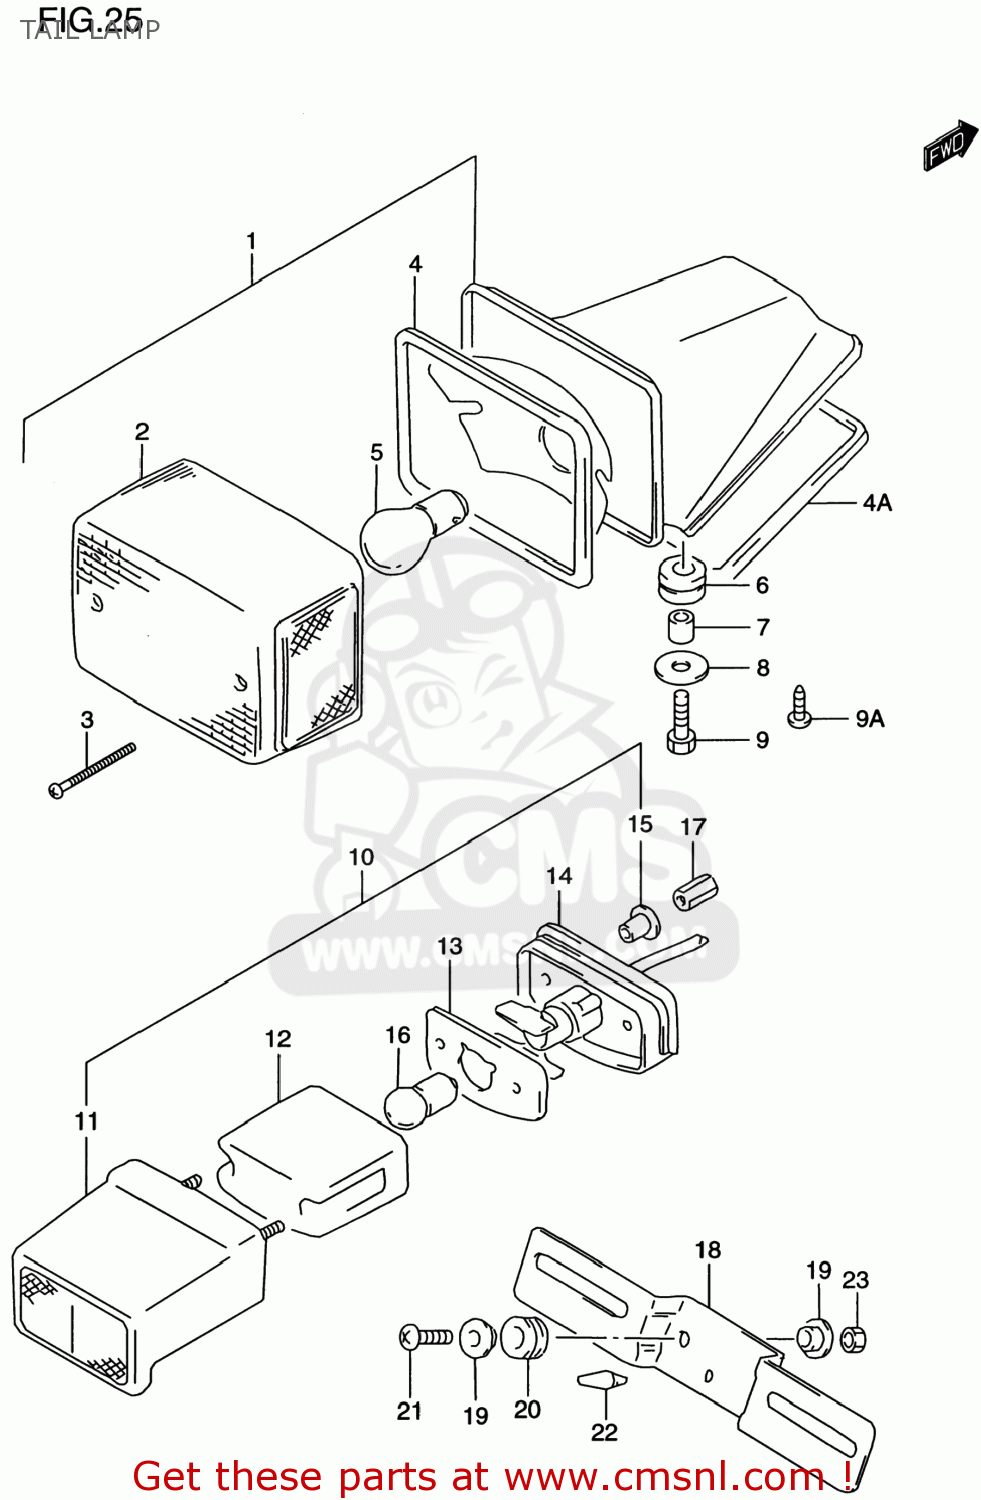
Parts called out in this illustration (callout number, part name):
1	LAMP ASSY,RR COMBINATION
2	LENS,TAIL LAMP
3	SCREW(4X45)
4	GASKET,LENS (NAS)
4A	GASKET (NAS)
5	BULB(12V21/5W)
6	CUSHION
7	SPACER(6.1X8X9.5)
8	WASHER(6.5X20X1.6)
9	BOLT
9A	SCREW
10	LAMP ASSY,LICENSE
11	COVER,LICENSE
12	LENS
13	GASKET,LICENSE LAMP (NAS)
14	CUSHION
15	SPACER
16	BULB(12V5W,BF150-40160A)
17	NUT
18	BRACKET,LICENSE PLATE
19	WASHER
20	CUSHION
21	SCREW
22	CUSHION
23	NUT 6MM
